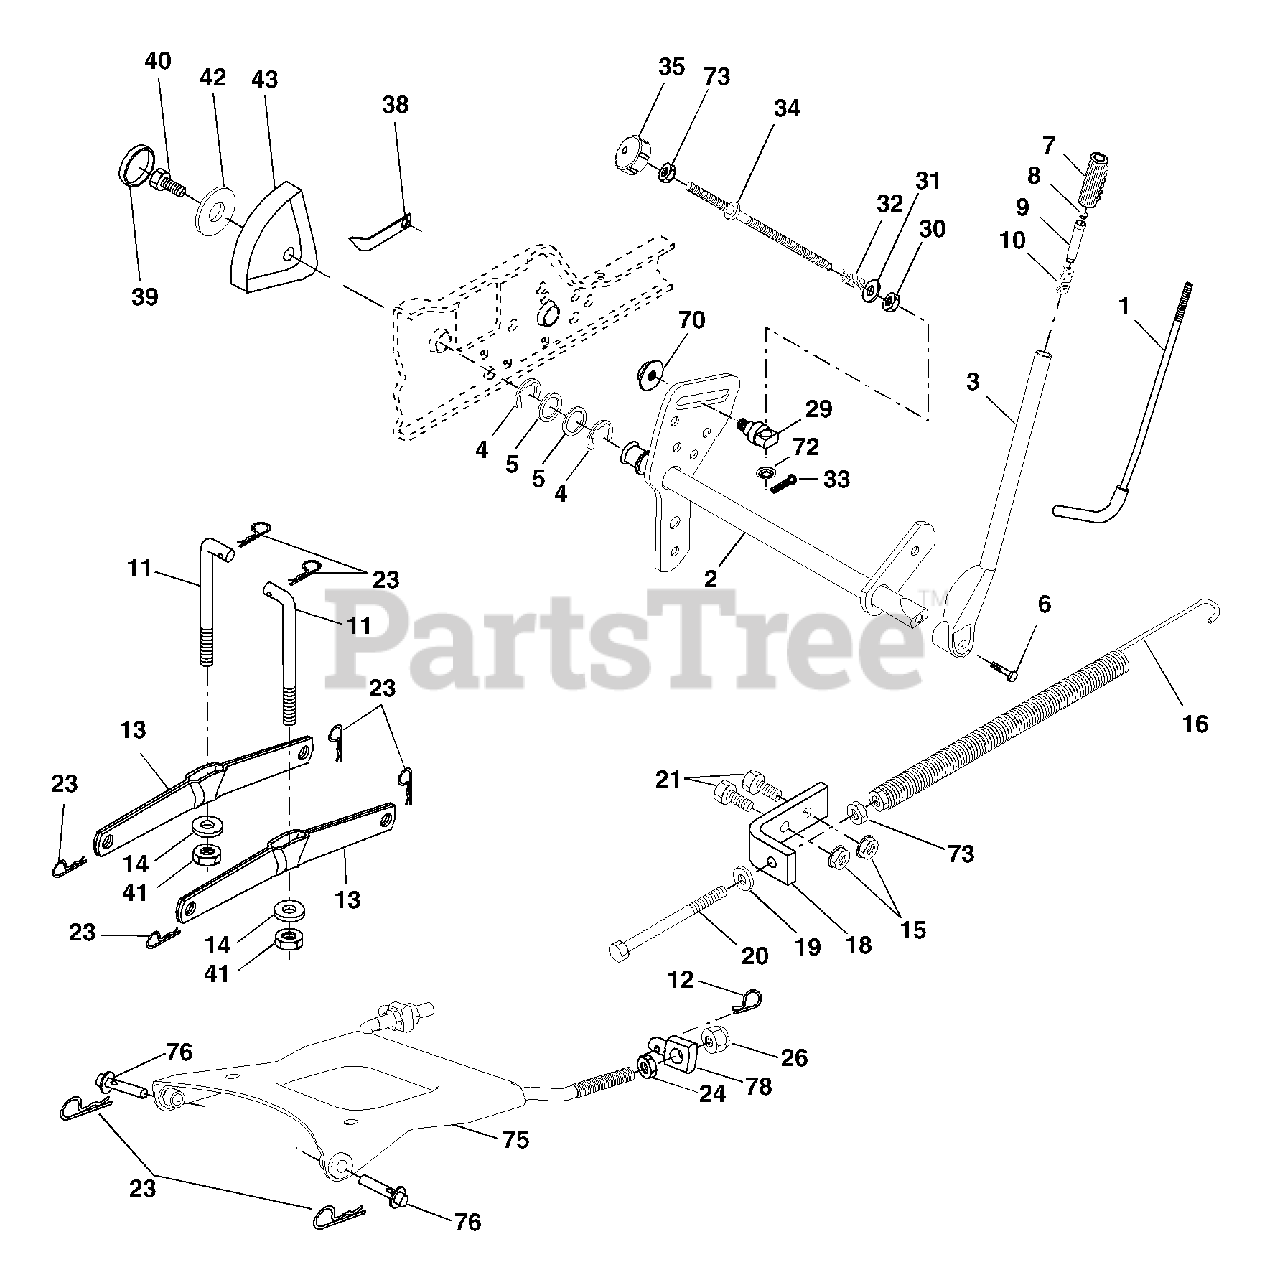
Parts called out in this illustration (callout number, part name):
1	Rod Asm., Lever
2	Shaft Asm., Lift Vgt
3	Lever Asm., Lift Rh
4	E-Ring Truarc #5133-87
5	Washer 29/32 x 1-1/4 x 16 Ga.
6	Bolt, Fin Hex 3/8-16 x 1-1/2
7	Grip, Handle Fluted
8	Button, Plunger
9	Plunger, Lever Lift
10	Spring 2-1/8"
11	Link Lift
12	Retainer,Spring
13	Arm, Suspension Vgt
14	Bearing Pivot Lift Tapered
15	Nut, Crownlock 3/8-16 Unc
16	Spring Asm., Assist Lift
18	Bracket, Spring Assist
19	Washer 13/32 x 13/16 x 16 Ga.
20	Bolt, Adjust Spring Assist
21	Bolt, Fin Hex 3/8-16 x 1
23	Retainer,Spring
24	Nut, Jam Hex 1/2-13 Unc
26	Nut, Crownlock 1/2-13 Unc
29	Trunnion Inf. Height
30	Nut, Special
31	Washer 13/32 x 5/8 x 16 Ga.
32	Spring, Compression Inf Hgt
33	Pin, Cotter 3/32 x 1/2
34	Rod, Adj Lift
35	Knob, Inf 3/8-16 Unc
38	Pointer, Height Indicator
39	Plug, Hole
40	Screw 5/16-18 x 3/4
41	Nut, Crownlock 3/8-24
42	Washer 11/32 x 1-1/2 x 10 Ga.
43	Scale, Indicator Height
70	Nut, Hexflange Lock
72	Nut, Push Phos & Oil
73	Nut Hex Jam 3/8-16 Unc
75	Plate Asm. Susp. Front
76	Pin Flange
78	Trunnion Front Susp.
